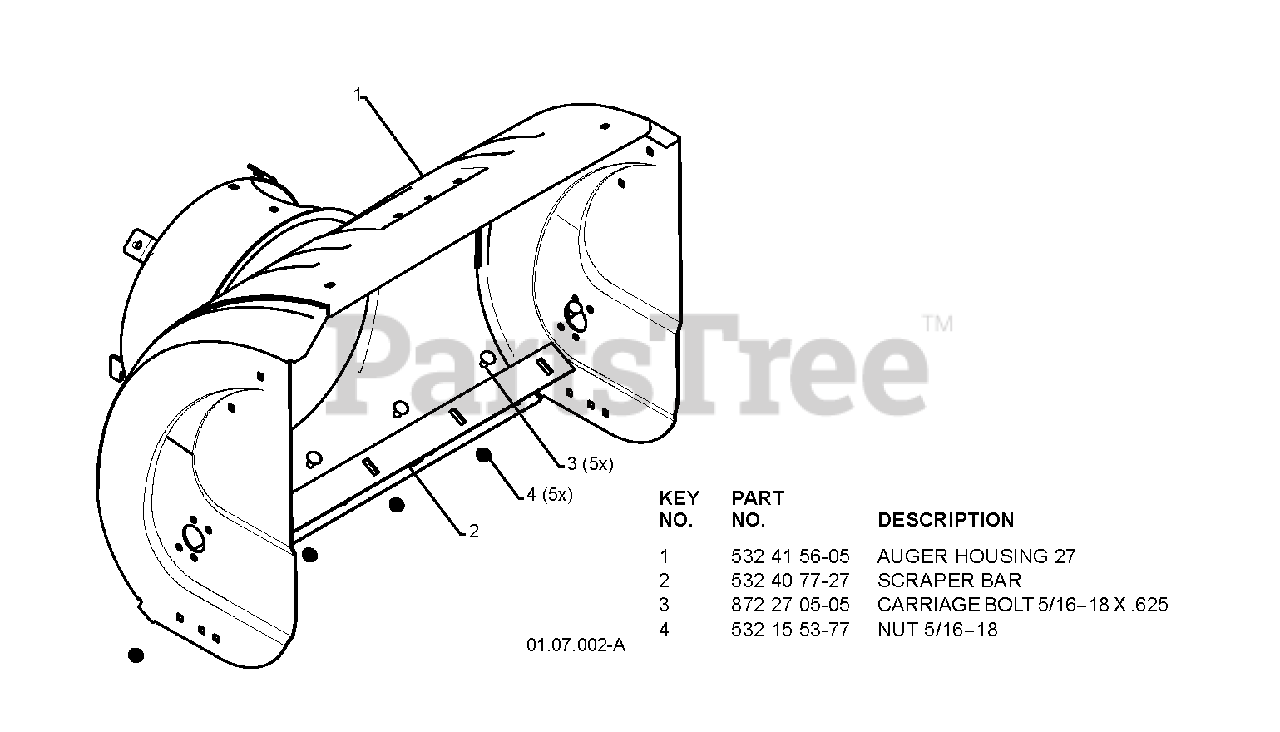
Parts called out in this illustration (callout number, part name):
2	BAR, SCRAPER
3	BOLT
4	NUT.FLANGE.5/16
